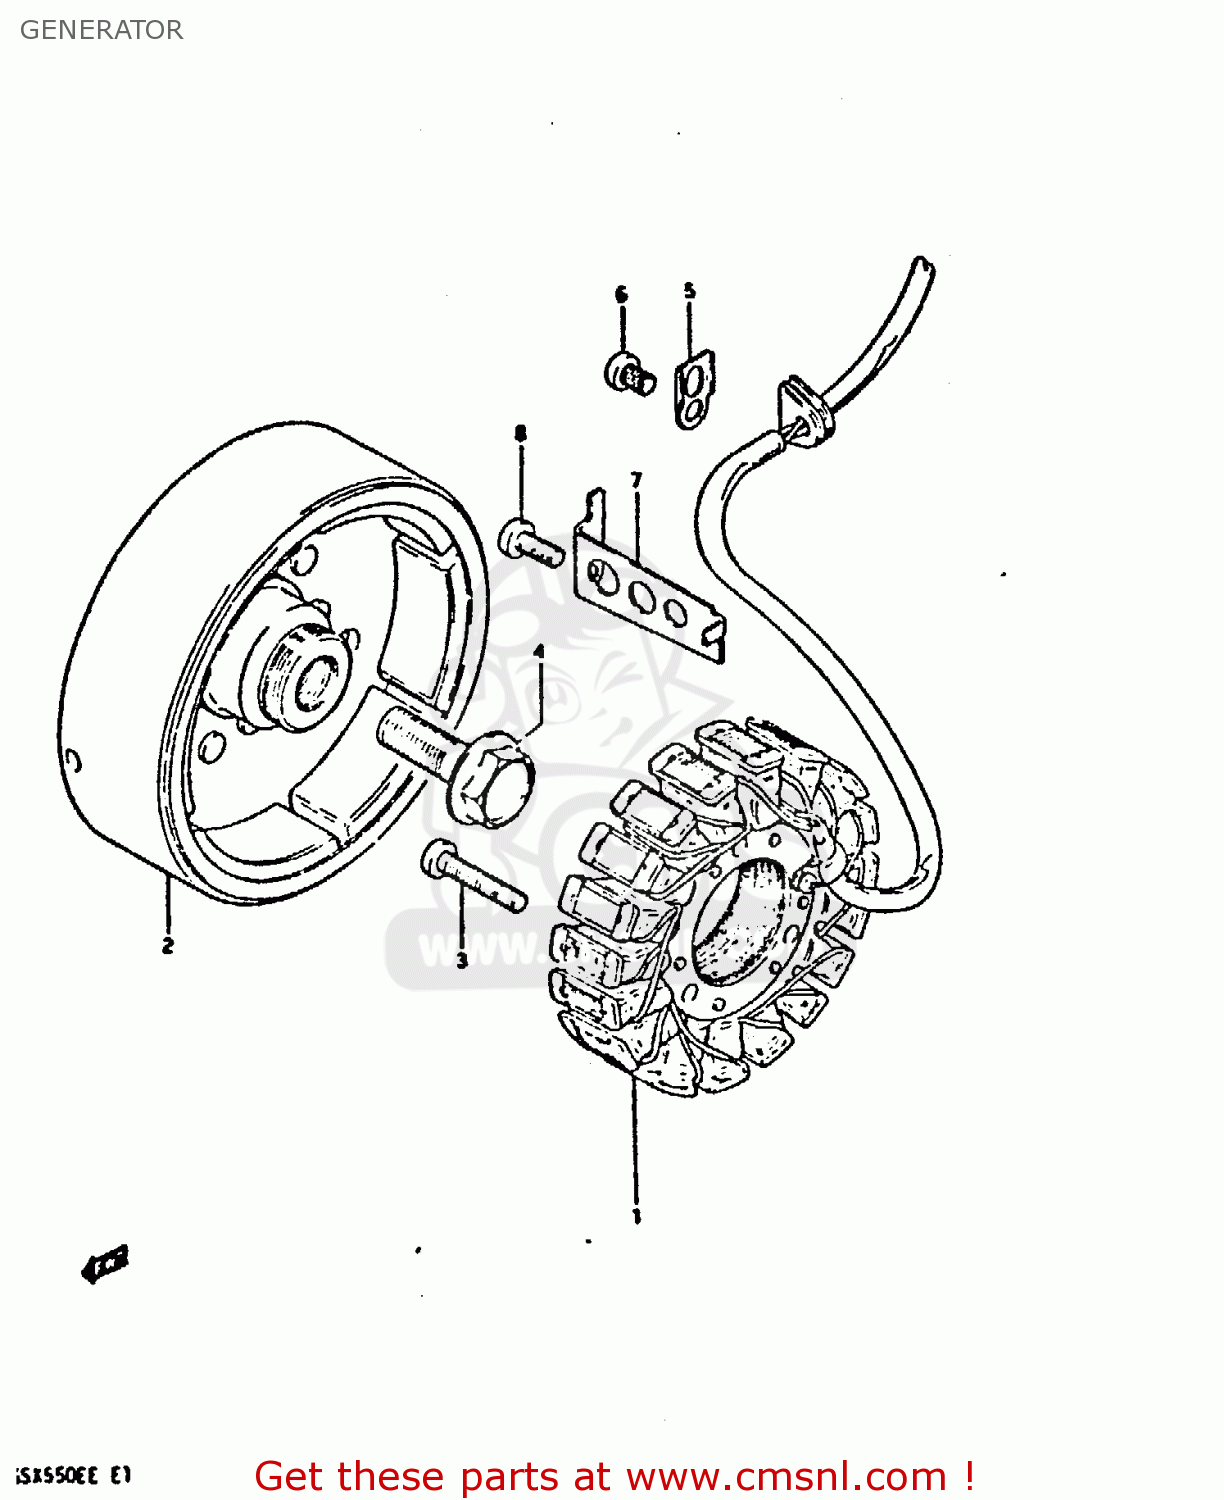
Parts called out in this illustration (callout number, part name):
1	STARTER ASSY
2	ROTOR ASSEMBLY
3	SCREW 6X30
4	BOLT(14X43)
5	CLAMP,GENERATOR LEAD WIRE
6	SCREW
7	CLAMP,GENERATOR LEAD WIRE
8	SCREW
